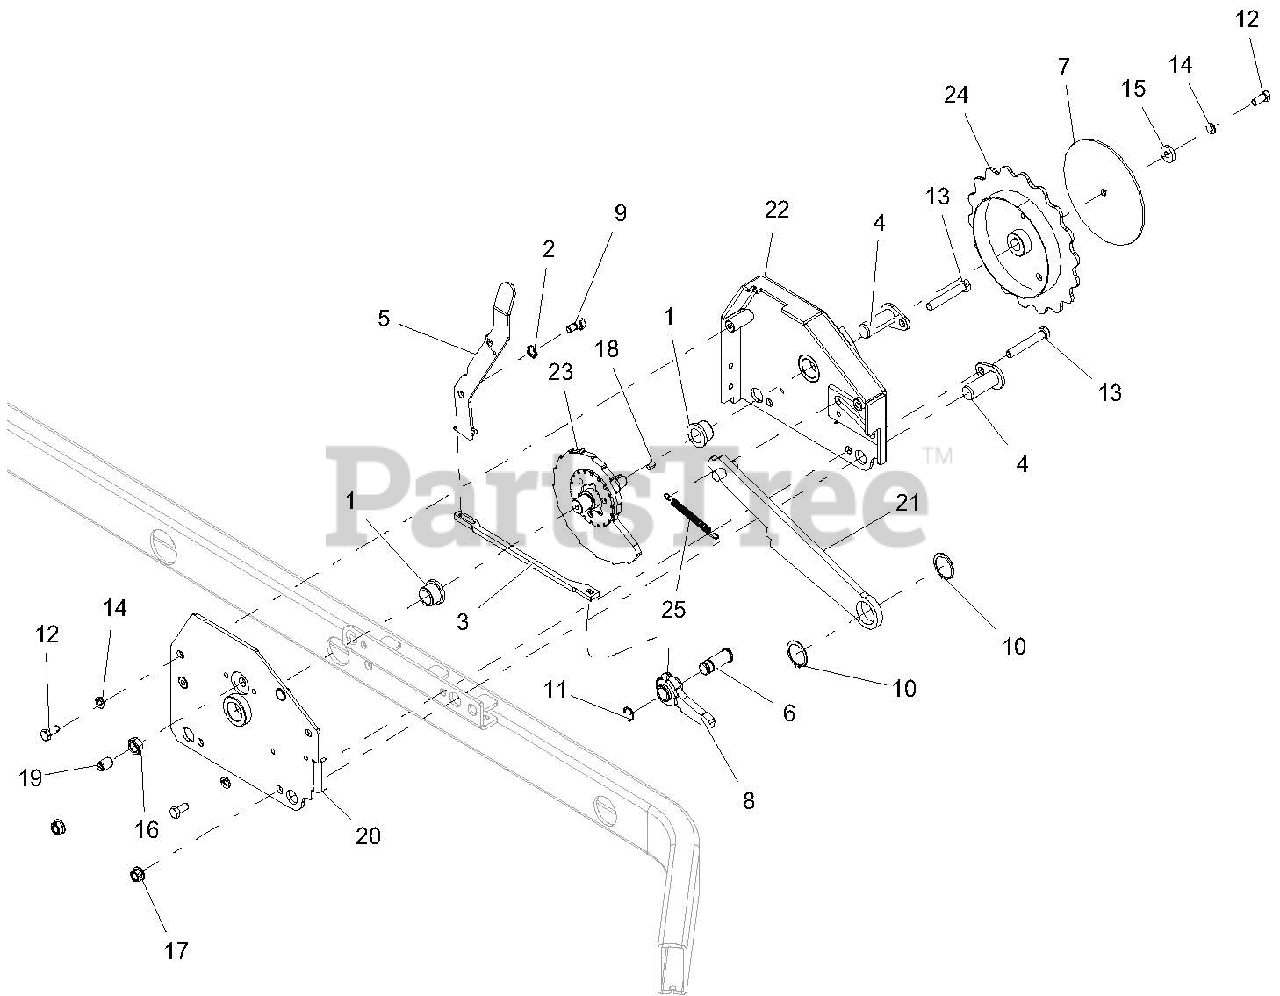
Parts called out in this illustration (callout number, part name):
1	BUSHING, FLANGE
2	WAVE WASHER .390X.655X.110
3	LINK, TRANSPORT LOCK
4	WLDMT, PIN
5	LEVER, TRANSPORT LOCK-BLACK
6	PIN, CLEVIS .625 SNAP RING
7	PLATE, DIAL-RED
8	WLDMT, LOCK PAWL
9	BOLT, SHLDR .38-16 x .437 HEX YZ
10	RG-RTNG-EXT 1.25x.050
11	RG-RTNG-EXT .625x.050
12	BLT-HEX .31-18X.75 GR5 YWZC
13	BLT-HEX .38-16X2.50 GR5 YWZC
14	WSHR-LK .31X.078 REG YWZC
15	WSHR-FL-STL .328X.87X.179 YWZC
16	NUT, JAM .500-13 YWZC
17	NUT, LK-CTR-FLG .38-16 YWZC
18	KEY-SQ .188X.188X.375
19	BALL SPRING PLUNGER, .500-13
20	WLDMT, HOC OUTER-RED
21	WLDMT, HOC LINK-BLACK
22	WLDMT, HOC INNER-RED
23	WLDMT, CAM HOC
24	WLDMT, DIAL, HOC
25	SPRG, EXTENSION
